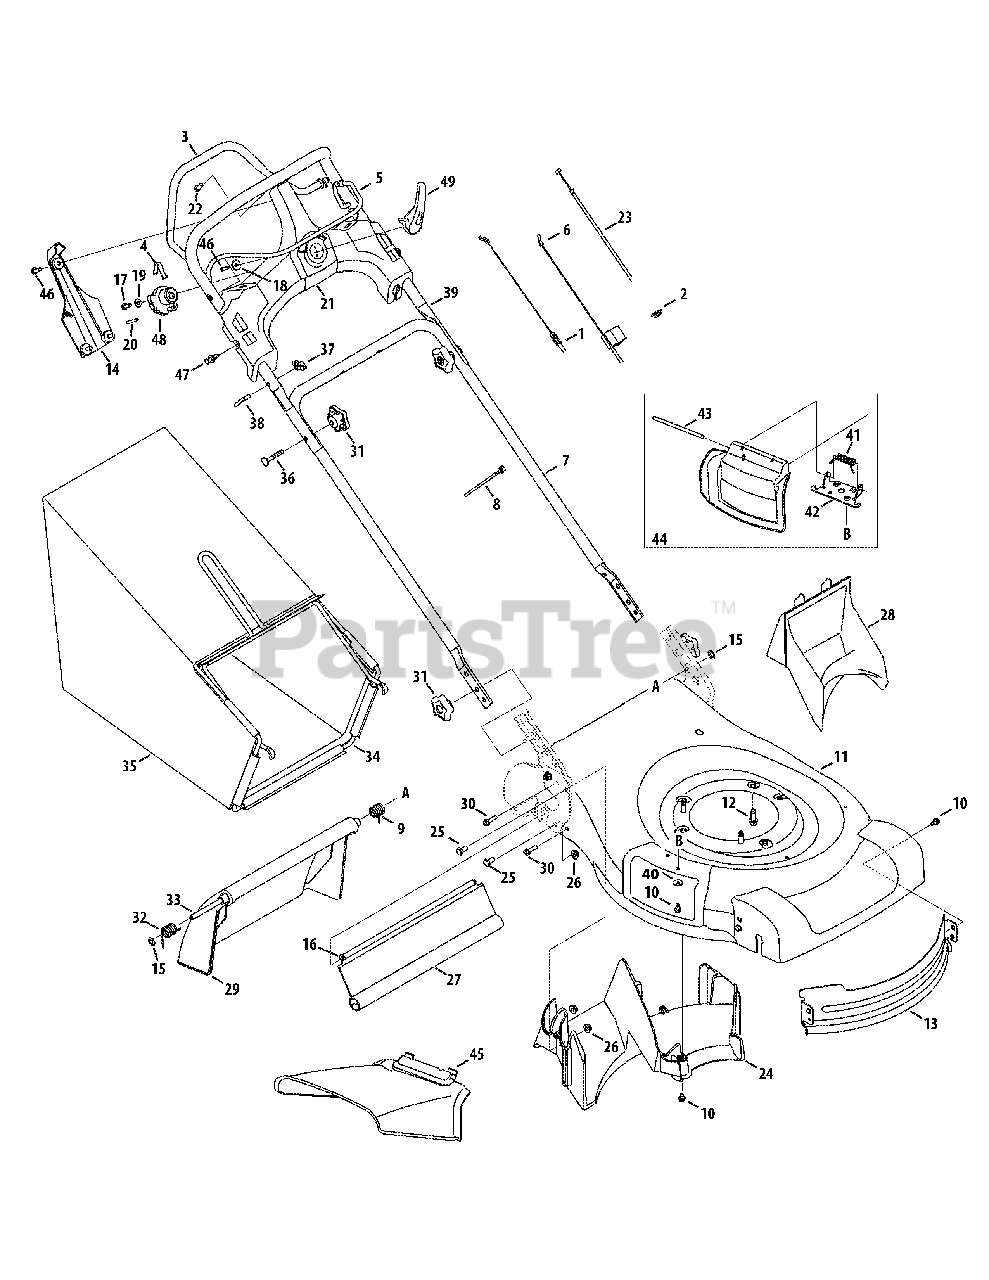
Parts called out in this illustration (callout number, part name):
1	Drive Cable
2	Rubber Grommet
3	Drive Control
4	Shift Spring
5	Blade Control
6	Control Cable
7	Lower Handle
8	Cable Tie
9	Torsion Spring, LH
10	TT Screw, 1/4-20 x .500
11	21-inch Deck
12	TT Screw, 3/8-16 x 1.00
13	Front Deck Baffle
14	Variable Spd. Cont. Panel Cover
15	Speed Nut
16	Screw, #10-16 x .500
17	Screw, 1/4-15 x .750
18	Washer, Flat, .250 x .750 x .119
19	Washer, Flat, .344 x .688 x .065
20	Dowel Pin
21	Variable Speed Control Panel
22	Screw, AB, 1/4-14 x .625
23	Variable Speed Cable
24	Rear Baffle
25	Screw, 5/16-18 x .625
26	Flange Lock Nut, 5/16-18
27	Trail Shield
28	Rear Mulching Baffle
29	Rear Door
30	Screw, 1/4-15 x 1.00
31	Star Knob
32	Torsion Spring, RH
33	Door Pivot Rod
34	Grass Catcher Frame
35	Grass Catcher
36	Carriage Bolt, 5/16-18 x 2.00
37	Wing Nut
38	Eye Bolt
39	Upper Handle
40	Bell Washer, .265 x .75 x .062
41	Torsion Spring
42	Chute Deflector Adapter
43	Hinge Pin
44	Mulch Plug Assembly
45	Side Discharge Chute
46	Screw, #12-16 x .75
47	Rivet, Plastic
48	4 Speed Actuator
49	Speed Selector Level
